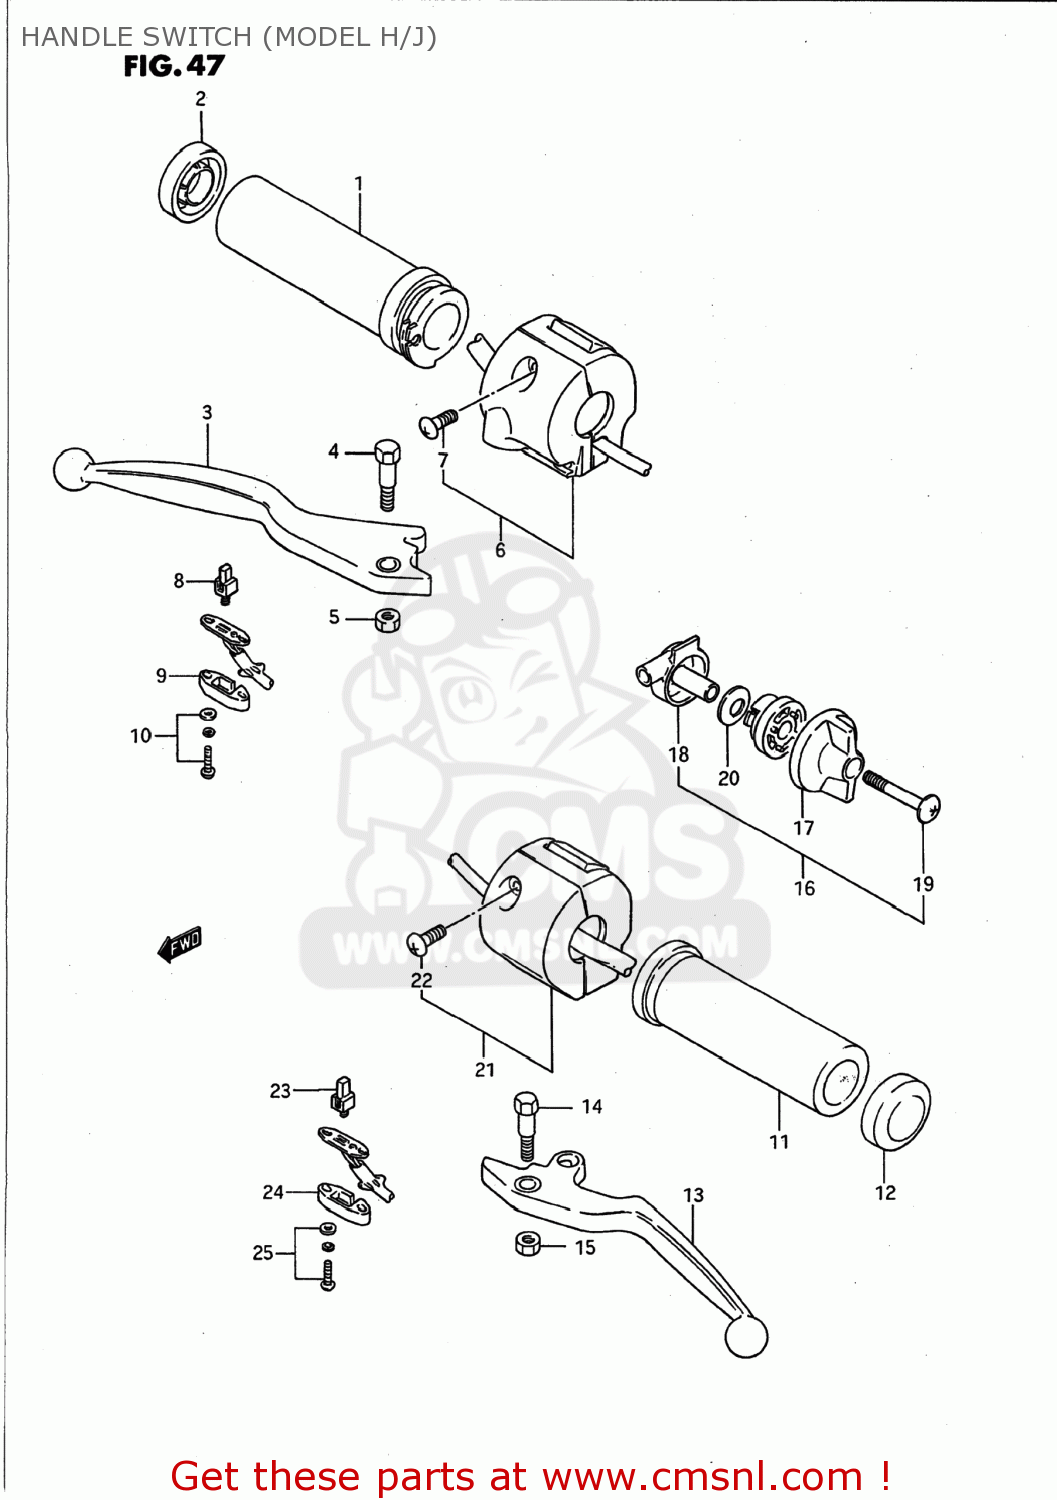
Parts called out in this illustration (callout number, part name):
1	GRIP,THROTTLE
2	CAP,GRIP END
3	LEVER,BRAKE
4	BOLT,LEVER
5	NUT 6MM
6	SWITCH ASSY,HANDLE,R
7	SCREW
8	CONTACT,SWITCH
9	COVER,BRAKE SWITCH
10	SCREW
11	GRIP,L
12	CAP,GRIP END
13	LEVER,CLUTCH
14	BOLT,LEVER
15	NUT 6MM
16	LEVER ASSEMBLY,STARTER
17	CLAMP,REAR BRAKE CABLE
18	BODY,STARTER
19	SCREW
20	WASHER,ADJUSTER
21	SWITCH ASSEMBLY,HANDLE,LEFT
22	SCREW
23	CONTACT,SWITCH
24	COVER,CLUTCH SWITCH
25	SCREW
